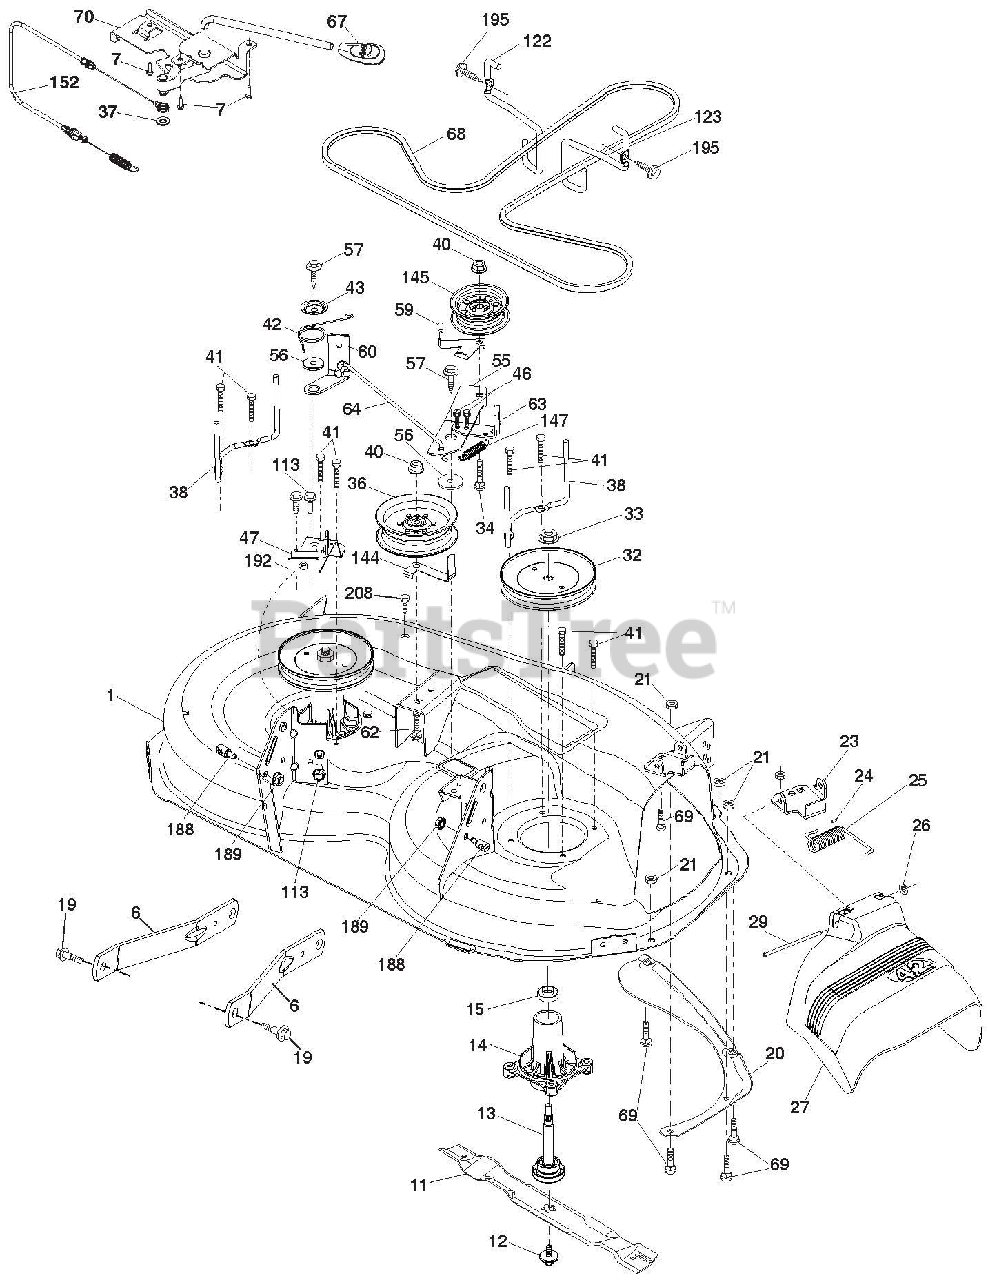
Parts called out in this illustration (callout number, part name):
1	DECK.WELDMENT.42"N/GWB
6	ARM.SUSPENSION.MOWER.REAR.LD
11	BLADE.MOWER.42"HI LIFT PREMIUM
12	SCREW 7/16-20 X 1
13	SHAFT ASM
14	HOUSING.MANDREL.4PT.SERVICE
15	BEARING
19	BOLT.SHOULDER
20	BAFFLE.VORTEX.42.STD/HEAVY DTY
21	Nut, Hex, Crownlock 5/16-18
23	BRACKET.DEFLECTOR.38/42"2005
24	CAP.SLEEVE..80X.112.BLK.MOWER
25	SPRING.TORSION.DFL.38/42/46.GR
26	NUT.PUSH.PHOS.& OIL
27	SHIELD.DEFLECTOR.
29	ROD.HINGE.42/46"
32	PULLEY.MANDREL.5.438 PD.42"
32	MANDREL ASM
33	NUT.FLANGE.LOCK.TOP
34	BOLT.CARR.SH.3/8-16X1-1/2.GR5
36	PULLEY.IDLER.4.50.RAW
37	WASHER.13/32 X 13/16 X 16 GA.
38	KEEPER.BELT.MANDREL.PULLEY
40	Nut, Hex, Flangelock 3/8-16
41	HEX HEAD BOLT
42	SPRING.TORSION.BRAKE
43	SPRING.TORSION.RETAINER
46	SCREW.THD.ROLL.1/4-20 X 5/8
47	BRACKET.CLUTCH.CABLE
55	IDLER.ARM
56	SPACER.RETAINER
57	SCREW.3/8-16X1.SMGML.TAP/R.BLK
59	GUARD.TUV.IDLER
60	ARM.BRAKE.MOWER.42"
62	BOLT.RD.HD.SQ.NK.3/8-16UNC X 2
63	ARM.BRAKE.MOWER
64	LINKAGE.BRAKE
67	HANDLE.CLUTCH.CABLE.LT TEX.428
68	BELT.DRIVE.100.97"
69	BOLT.RDHD.SQNK.5/16-18 X 5/8
70	CLUTCH ASM.MANUAL.LT.TEX
113	BOLT.5/16-18HEX.WHS.HD.LCKSERR
122	KEEPER.BELT.ENGINE.LH.LT.TEX
123	KEEPER.BELT.ENGINE.RH.LT.TEX
144	KEEPER.BELT.MOWER
145	PULLEY.IDLER 48"PRIMARY
147	SPRING.RETURN
152	CABLE.CLUTCH.MANUAL
188	STUD.FASTNER.W/'D'ANTI-ROTATIO
189	Nut, Lock Hex Flange 5/16-18 u
192	BRACKET.BRAKE.STAND.LH
195	SCREW.HEXWSH THDR3/8-16X3/4.BL
208	SCREW.THDROL.3/8-16X1/2.TYT.BL
